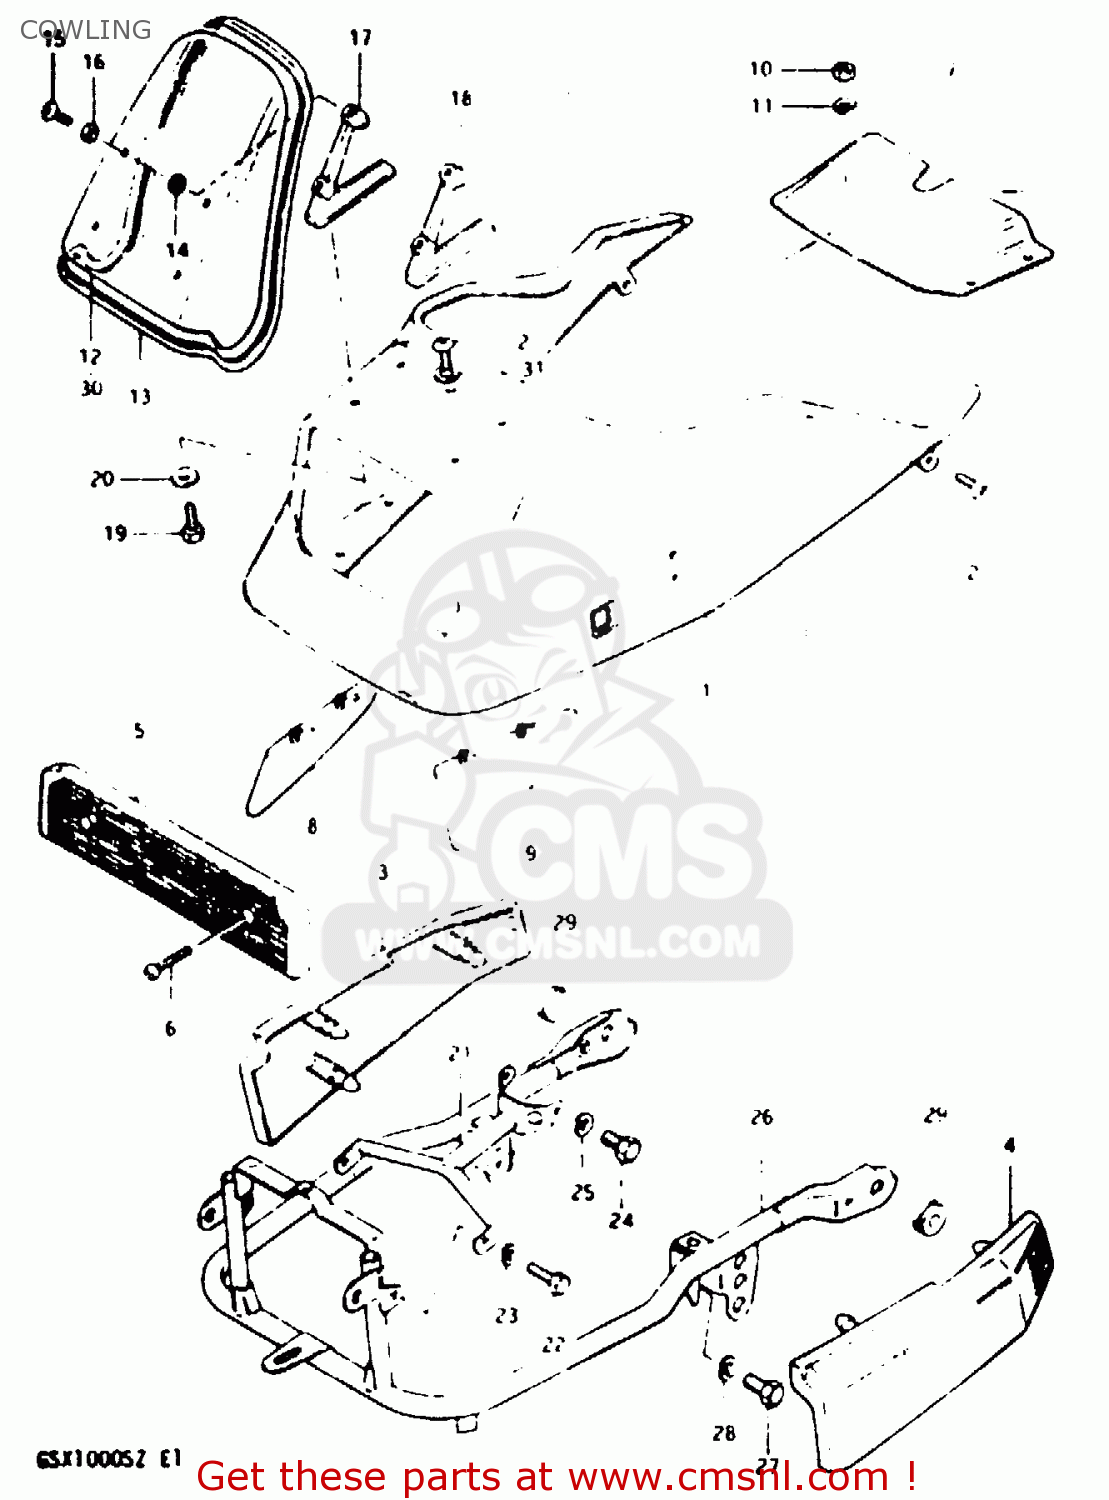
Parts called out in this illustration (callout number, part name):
1	BODY, COWLING (BLACK/SILVER)
2	SCREW 6X12
3	COVER, RH (SILVER)
4	COVER, LH (SILVER)
5	COVER,COWLING LOWER
6	SCREW
7	COVER,COWLING LOWER FR
8	WING,COWLING RH
9	WING,COWLING LH
10	NUT
11	LOCK WASHER
12	WINDOW,COWLING
13	MOLD,COWLING
14	CUSHION
15	SCREW
16	WASHER(5.2X11X1)
17	BRACE,COWLING WINDOW RH
18	BRACE,COWLING WINDOW LH
19	BOLT
20	WASHER(6.5X16X1.2)
21	BRACKET,COWLING UPPER
22	BOLT, UPPER
23	LOCK WASHER
24	BOLT
25	LOCK WASHER
26	BRACE,COWLING RR
27	BOLT 8X12
28	LOCK WASHER
29	CUSHION
31	WASHER
